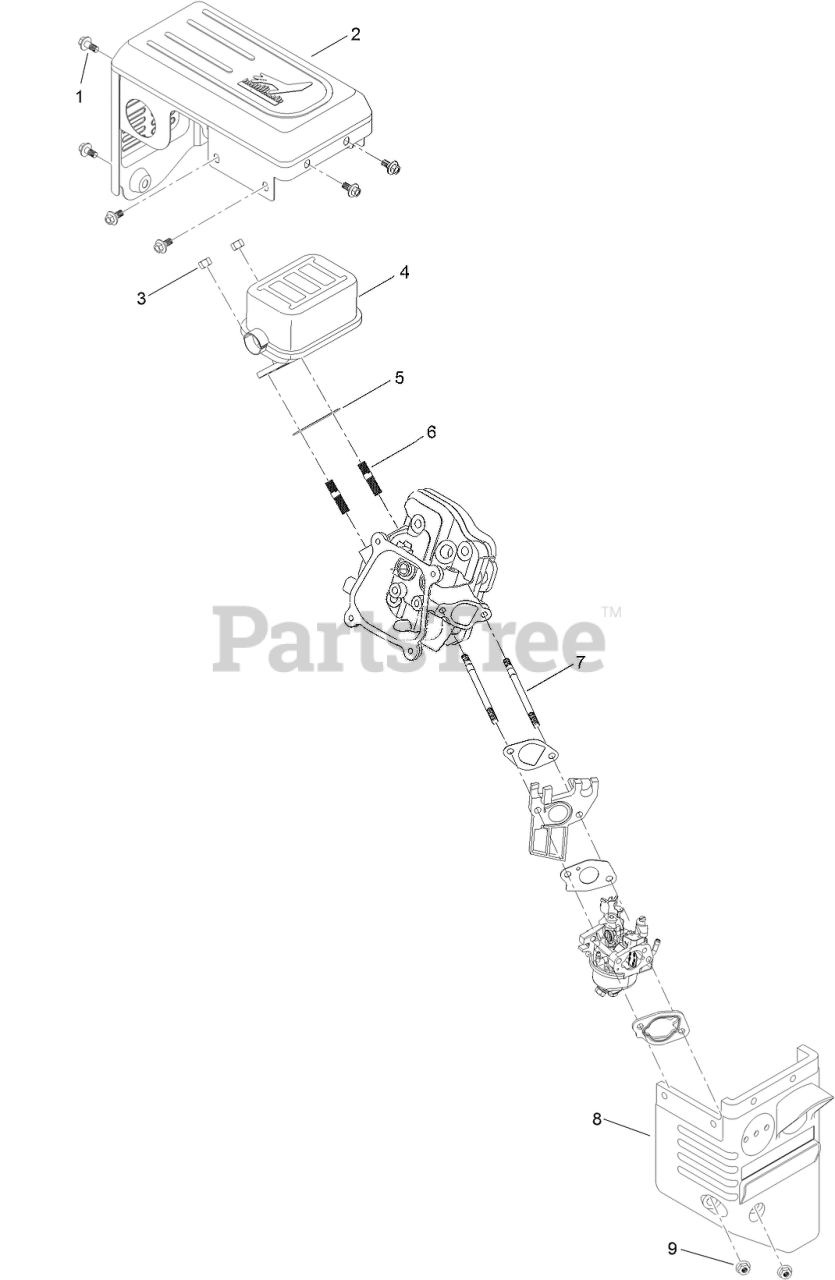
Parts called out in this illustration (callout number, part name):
1	SCREW-HHF
2	GUARD-MUFFLER
3	NUT-HH
4	MUFFLER ASM
5	GASKET-EXHAUST
6	STUD-EXHAUST
7	STUD-INTAKE
8	BOX-HEATER
9	NUT-FLANGE
